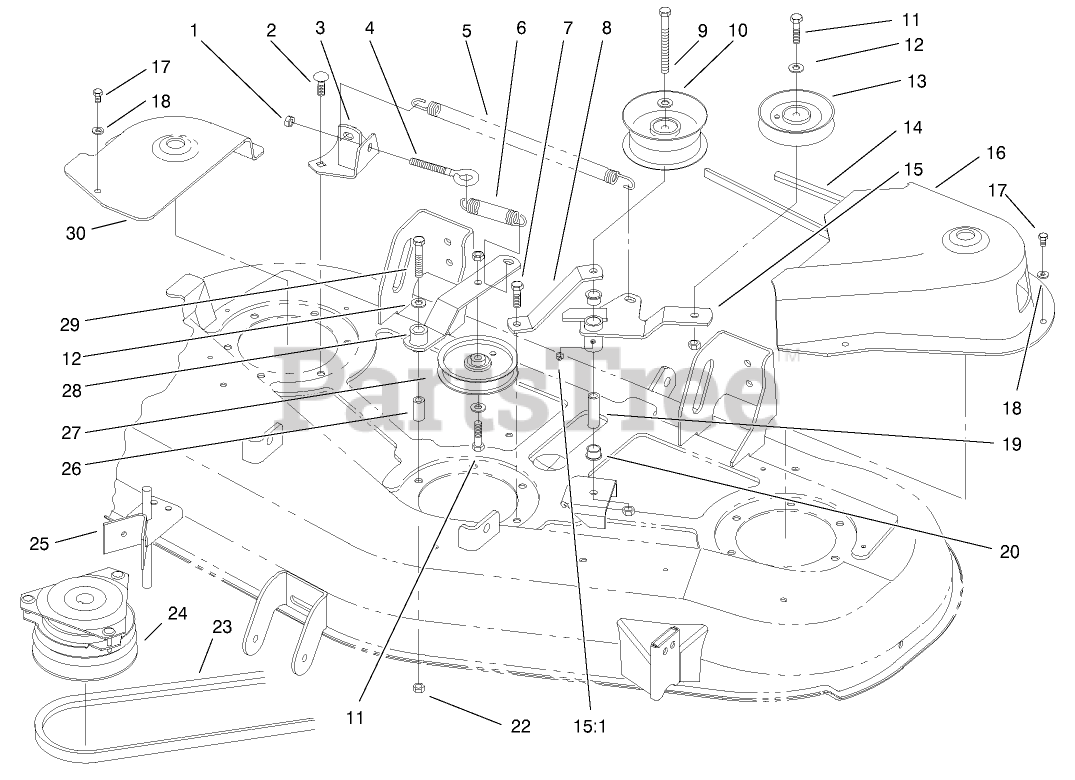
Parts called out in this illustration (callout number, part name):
1	NUT-LOCK, NI
2	SCREW-CARR
3	BRACKET-SPRING
4	BOLT-EYE
5	SPRING-EXTENSION
6	SPRING-EXTENSION
7	SCREW-HH
8	STRAP-SUPPORT
9	SCREW-HH
10	PULLEY-IDLER
11	SCREW-HH
12	WASHER-FLAT
13	PULLEY-IDLER
14	V-BELT
15	IDLER ARM ASSEMBLY
15:1	FITTING-GREASE
16	COVER-BELT, LH
17	SCREW-HWH
18	WASHER-FLAT
19	SPACER
20	BUSHING
22	NUT-HF
23	BELT - V
24	CLUTCH-PTO
25	DECK UPSTOP ASM
26	SLEEVE
27	PULLEY-IDLER
28	IDLER ARM ASM
29	SCREW-HH
30	COVER - BELT, RH
